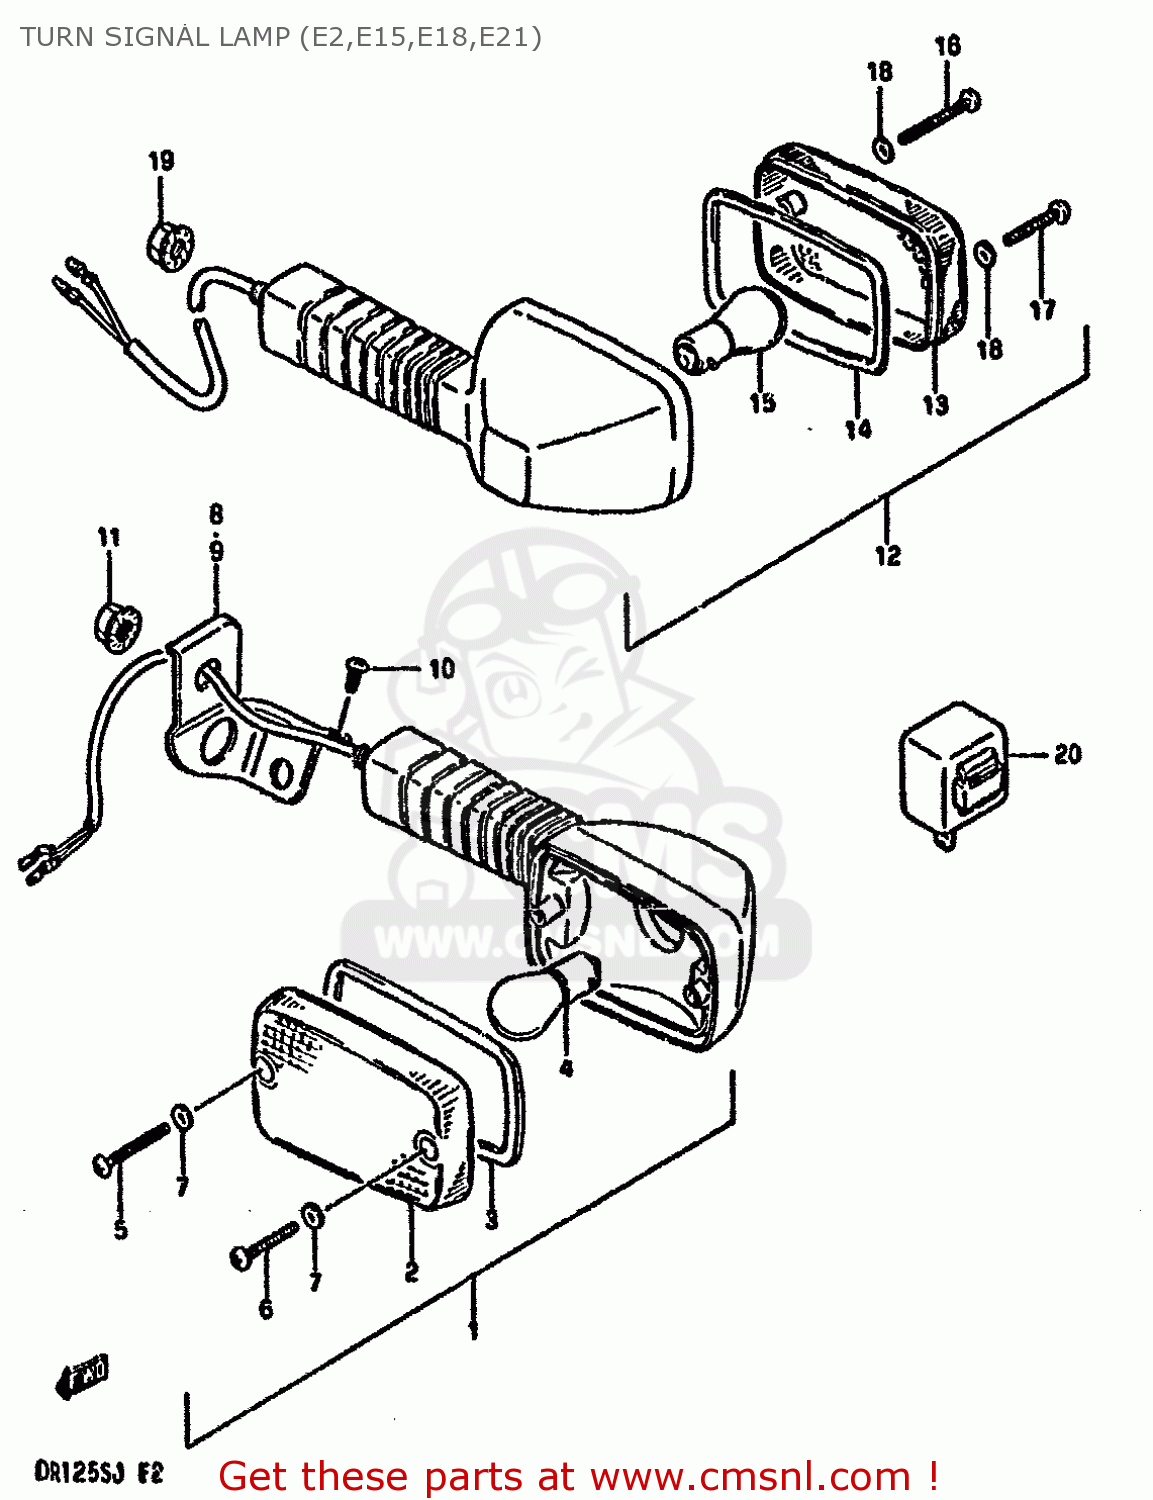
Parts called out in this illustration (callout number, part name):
1	LAMP ASSY,FRONT TURN SIGNAL
2	LENS,FR
3	GASKET (NAS)
4	BULB(12V21W)
5	SCREW,TURN SIG LENS FITTING
6	SCREW
7	GASKET (NAS)
8	BRACKET,FRONT TURN SIGNAL,RIGHT
9	BRACKET,FRONT TURN SIGNAL
10	SCREW
11	NUT
12	LAMP,RR TURNSI
13	LENS,RR
14	GASKET (NAS)
15	BULB(12V21W)
16	SCREW,TURN SIG LENS FITTING
17	SCREW
18	GASKET (NAS)
19	NUT
20	RELAY ASSEMBLY,TURN SIGNAL
